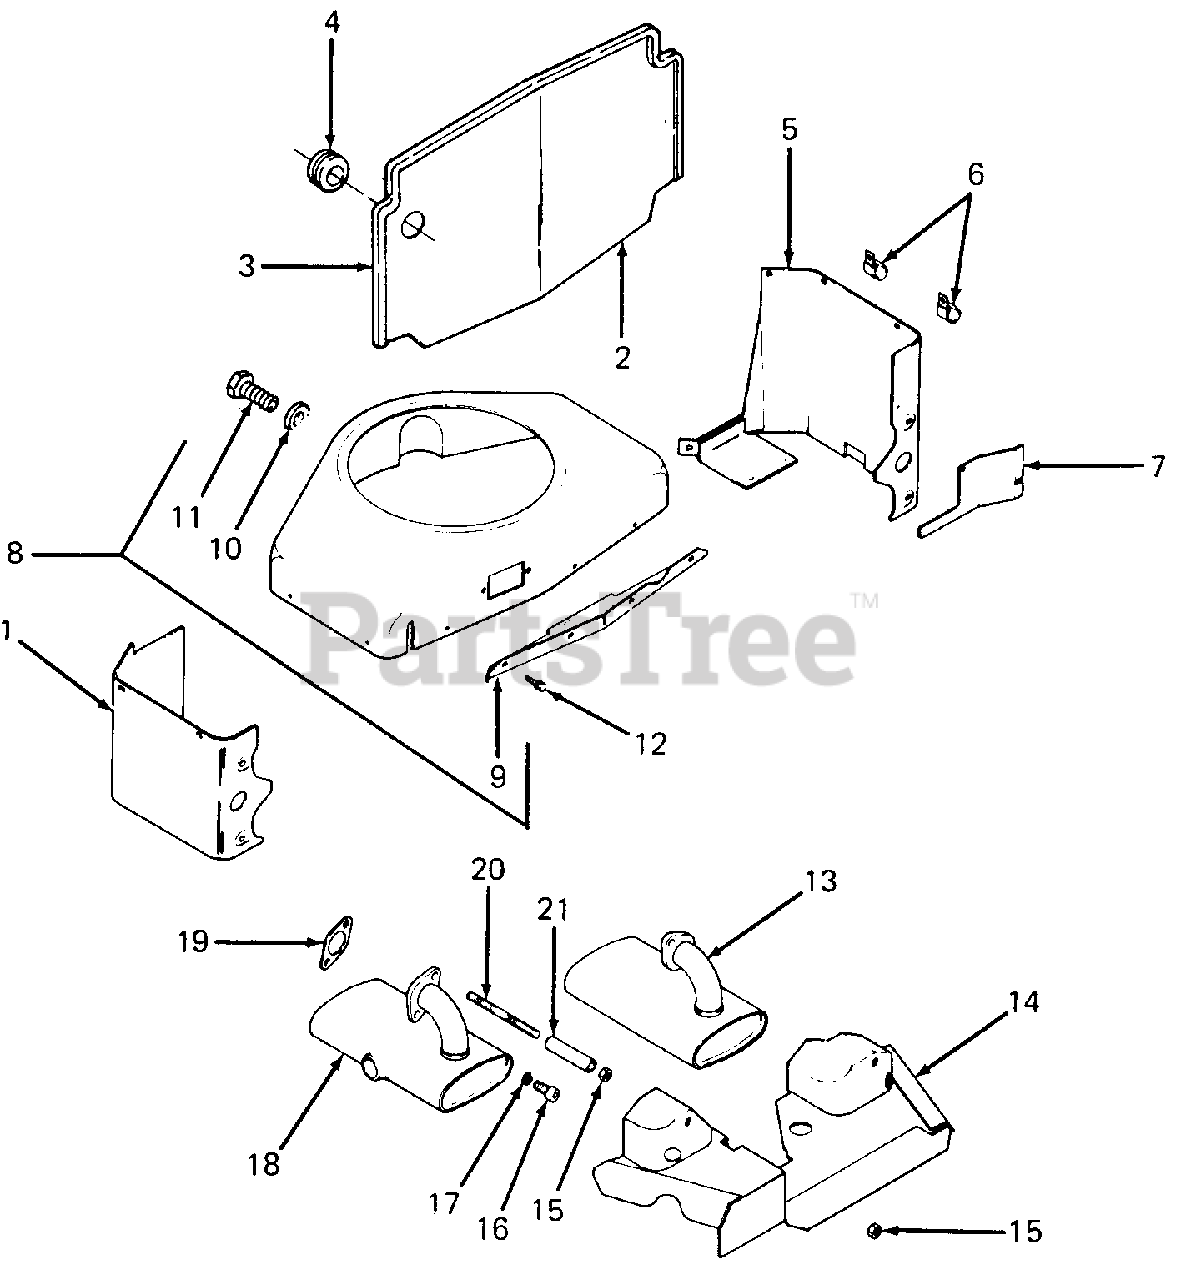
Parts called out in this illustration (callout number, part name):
1	Baffle, Cylinder Head, RH
2	Baffle, Engine Heat
3	Seal, Engine Heat Baffle
4	Bushing, Snap, 3/4
5	Baffle, Cylinder Head, LH
6	Clip
7	Top, Cylinder, LH
8	Housing Kit, Blower
9	Support, Upper Housing
10	Washer, Flat
11	Screw, Self Tapping, 1/4-20 X 5/8
12	Screw, Hex Wash Hd, 1/4-20 X 7/16
14	Shield, Heat
15	Nut, Hex, 5/16-18
16	Screw, Hex Socket Hd, 5/16-18 X 3/4
17	Washer, Lock, 5/16
19	Gasket, Exhaust
20	Stud, 5/16-18 X 4
21	Spacer, 5/16 I.D. X 9/16 O.D.
